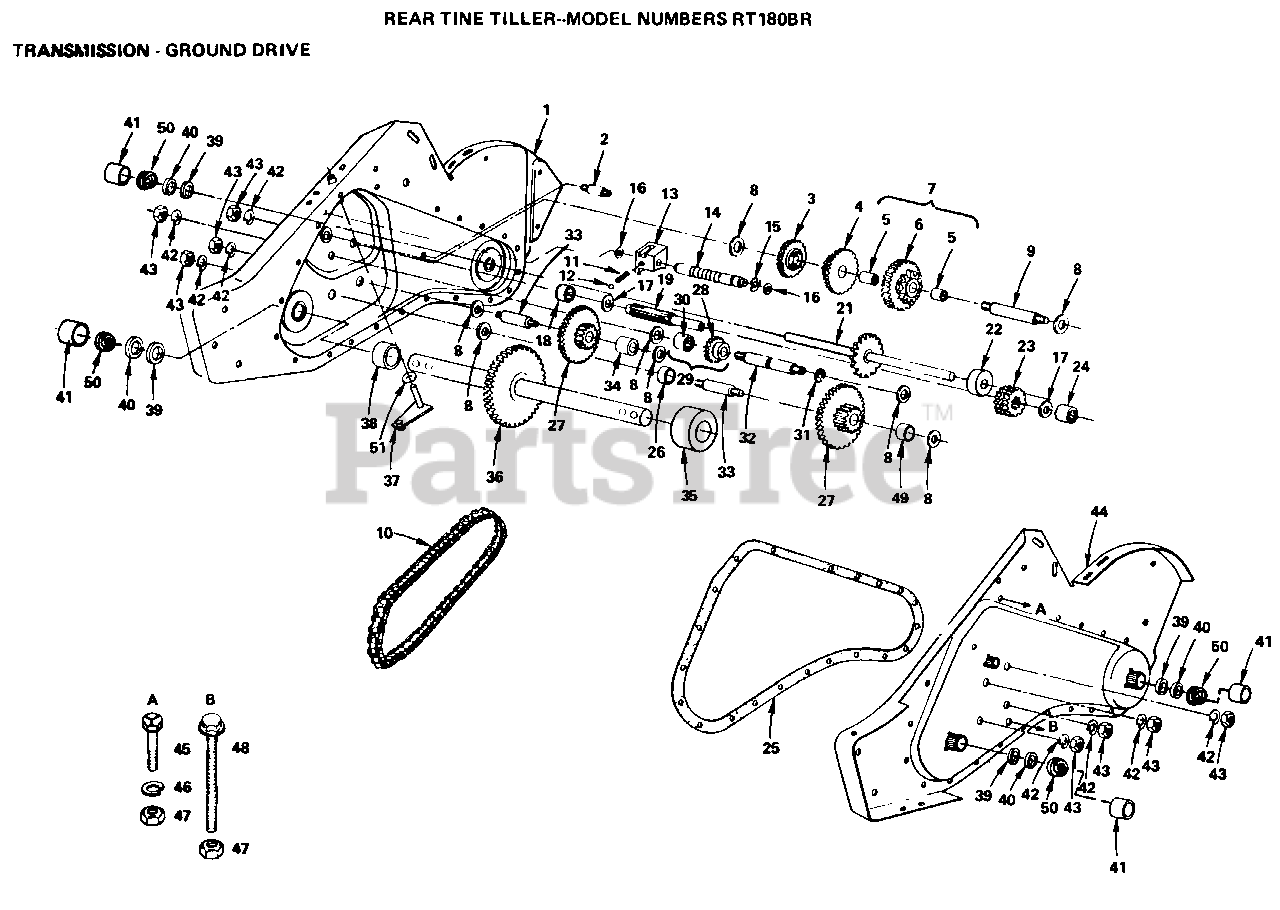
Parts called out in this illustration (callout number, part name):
2	BOLT TI
3	REVERSE GEAR TI
4	CLUSTER GEAR TI
5	"CRT, BEARING"
7	SPROCKET ASSY TI
8	WASHER
9	REDUCTION SHFT TI
10	CHAIN TI
11	SPRING-SHIFT CRT
13	SHIFT FORK TI
14	SHIFT SHAFT TI
15	KLIP RING
17	"T, BEARING"
18	"TI, BEARING"
19	SHAFT INPUT T
21	SHAFT TINE CRT
22	SPACER CRT
23	INPUT PINION TI
24	NEEDLE BRNG LT
25	GEARCASE GSKT TI
26	SPACER CRT
27	GEAR CLUSTER CRT
28	REVERSE GEAR TI
29	GEAR ASSY TI
30	NEEDLE BEARING TI
31	KLIP RING
32	REVERSE SHAFT TI
33	SHAFT CRT
34	SPACER CRT
35	SPACER CRT
36	SHAFT ASSY CRT
38	SPACER CRT
41	CUP.FORMED.
42	LOCKWASHER
43	NUT.ASF.HEX.7/16
45	BOLT
46	LOCKWASHER
47	NUT.HEX.5/16-18
48	BOLT TI
49	SPACER CRT
50	RING SPIRAL CRT
51	O-RING TI
